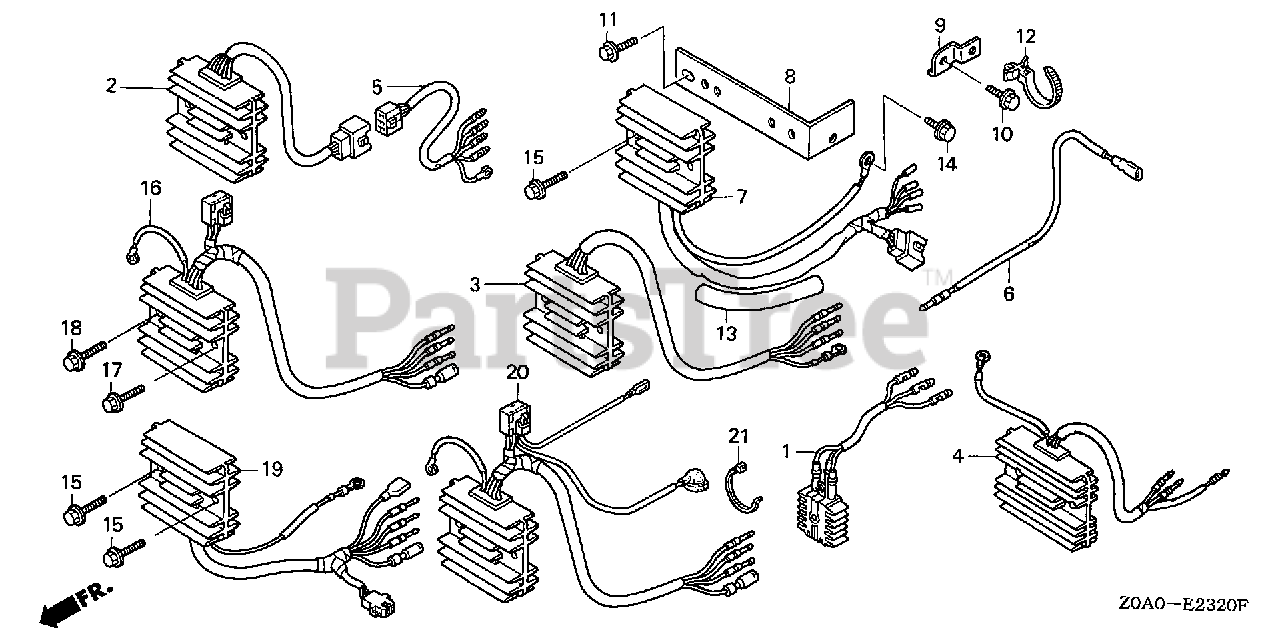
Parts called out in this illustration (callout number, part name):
6	SUB-WIRE HARNESS ASSY.
9	BASE, CLIP
10	BOLT, FLANGE (6X12) (CT200)
12	STRAP, CABLE (105MM) *NH1* (Honda Code 1685536). (BLACK)
13	TUBE, CORD
16	RECTIFIER ASSY., REGULATOR
17	BOLT, FLANGE (6X25) Use up to Engine SN 2056819.
18	BOLT, FLANGE (6X25)
